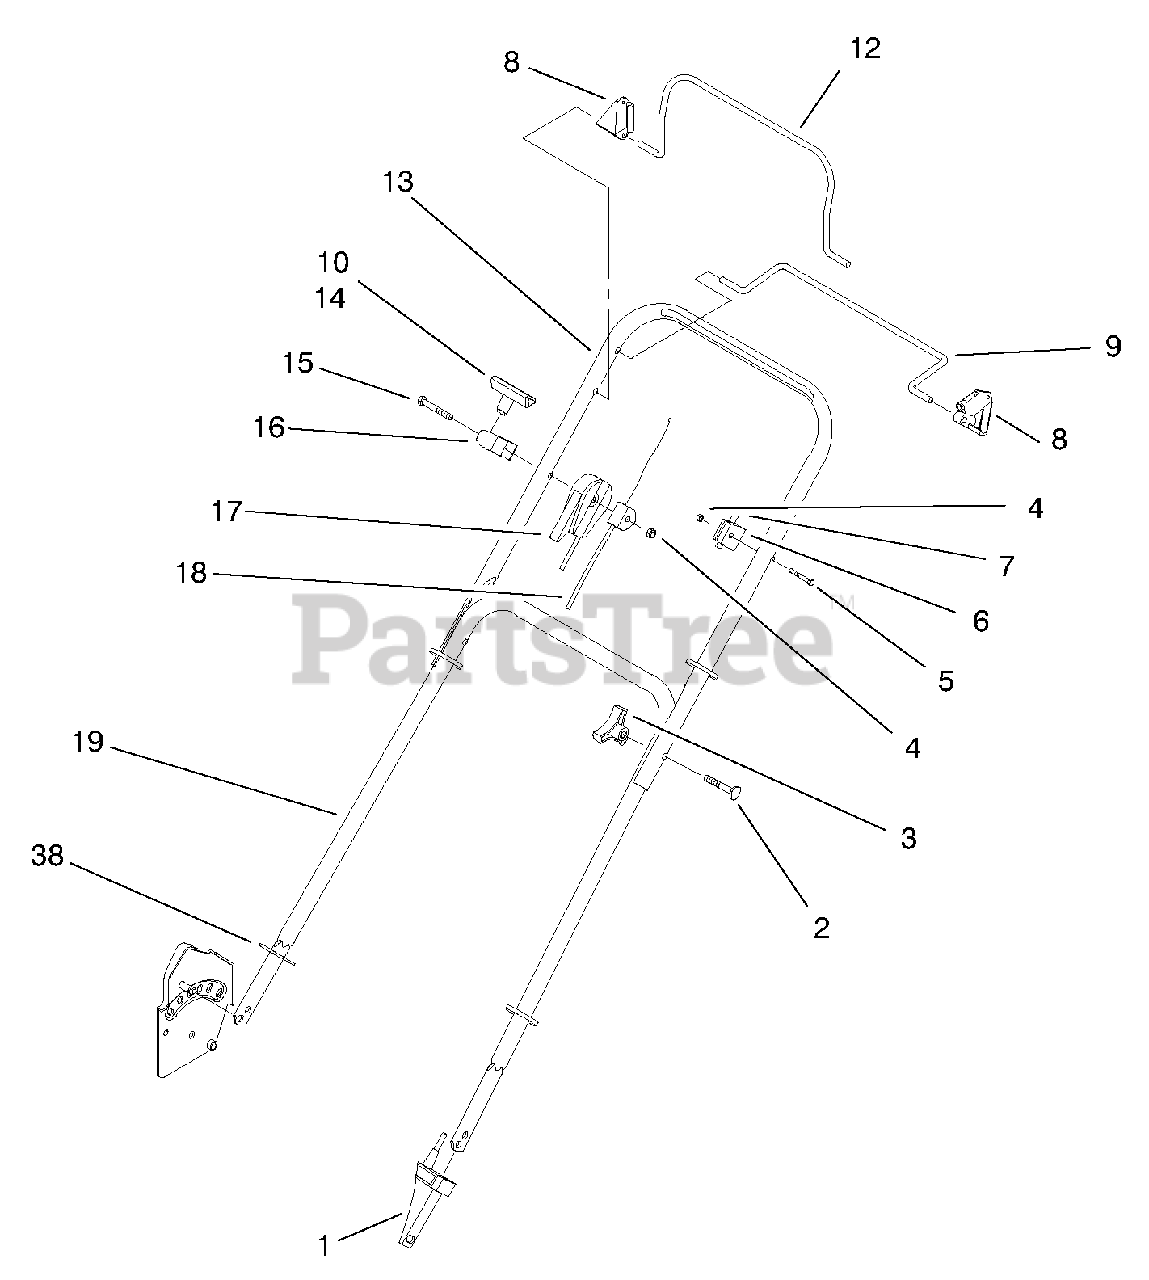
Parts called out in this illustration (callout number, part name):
1	Anchor-Cable
2	Screw-Handle
3	Knob
4	Nut-Lock
5	Screw-Handle
6	Anchor-Cable
7	Cable-Traction
8	Stop-Pivot
9	Bail-Sp Control
10	Staple-Handle
12	Bail-Flywheel Brake
13	Handle Section-Upper
14	Handle-Starter
15	Screw-HH
16	Guide-Rope
17	Cable-Throttle
18	ASM-Brake Cable
19	Handle Section-Lower
38	Handle-Guard
